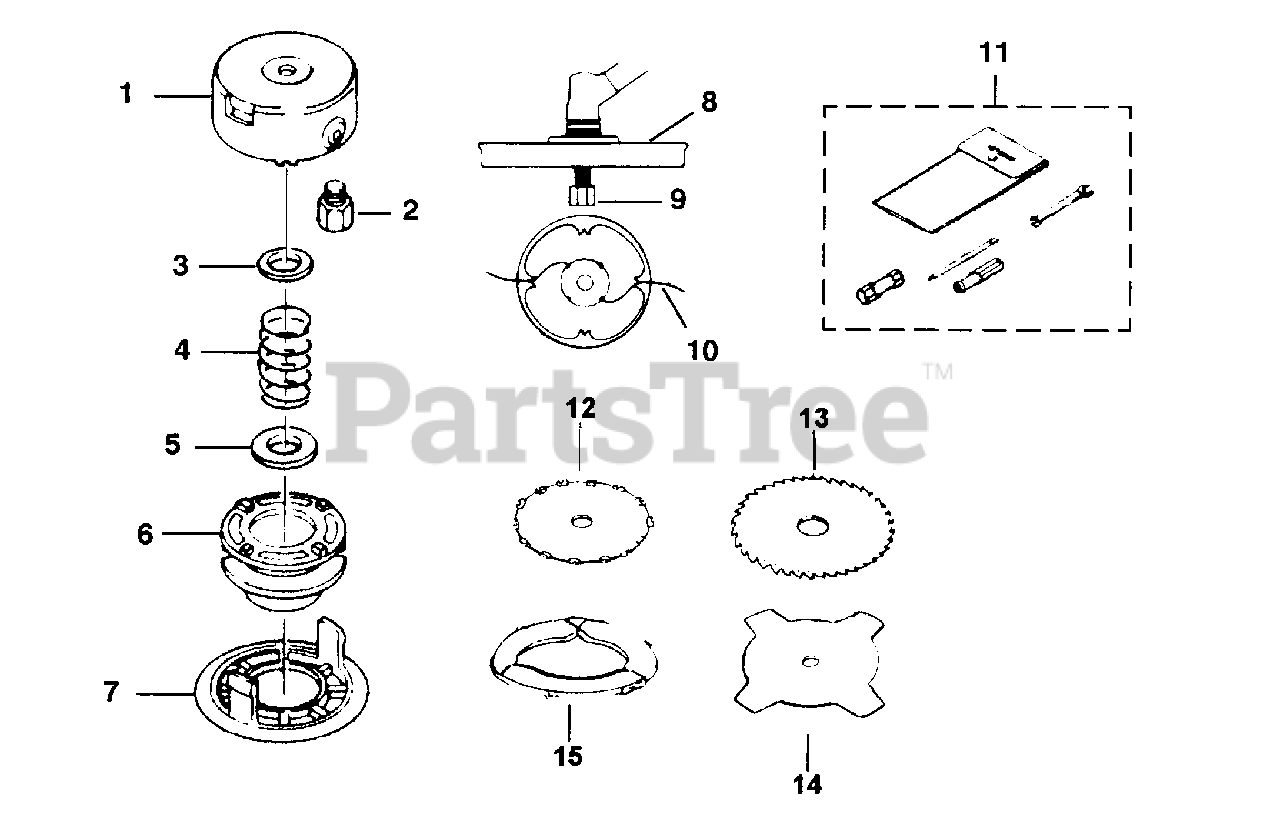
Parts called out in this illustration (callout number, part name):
1	HEAD BODY
2	ARBOR BOLT
3	SPRING PLATE
4	SPRING
5	SPRING PLATE
6	SPOOL
8	FIXED LINE HEAD ASSY.
9	ARBOR BOLT
10	GREEN LINE .080 X 20ft.
12	8" XRT BLADE
13	8" SAW BLADE
14	8" QUAD BLADE
15	BLADE COVER
